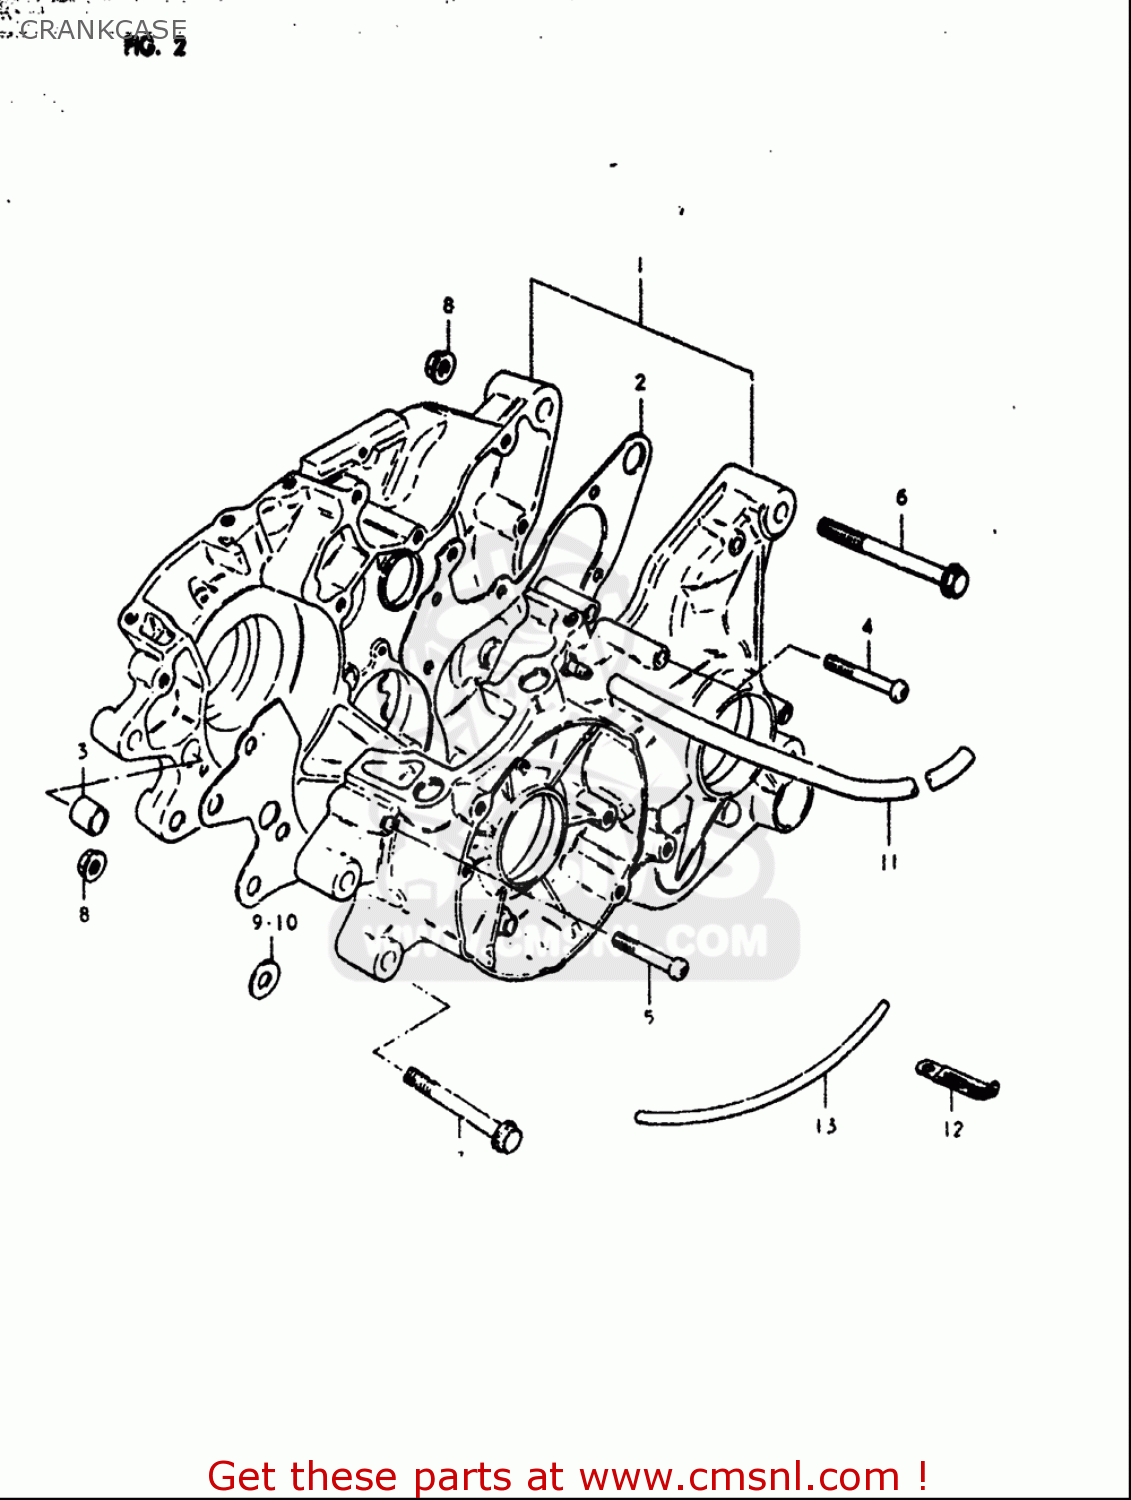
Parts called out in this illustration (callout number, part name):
2	GASKET,CRANKCASE (NAS)
3	PIN
4	SCREW
5	SCREW
6	BOLT
7	BOLT(8X67)
8	NUT
11	HOSE(5X8.2X2000)
12	CLAMP(L:65)
13	HOSE(4X7X600)
